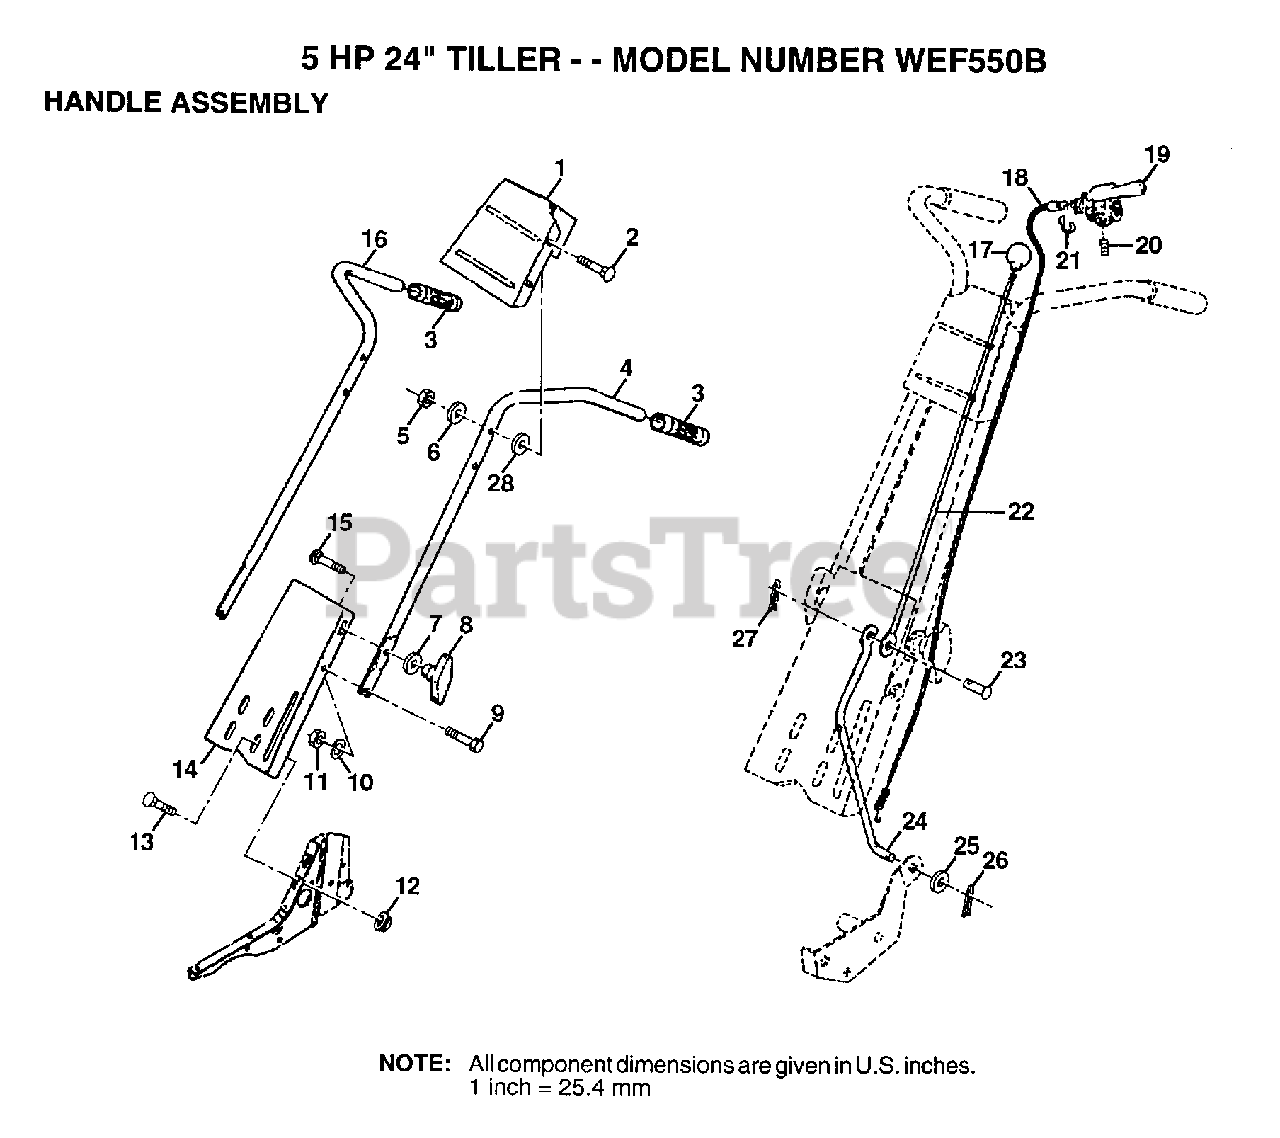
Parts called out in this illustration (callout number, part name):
1	HANDLE BRACKET
2	BOLT
6	WASHER
7	WASHER
8	KNOB HANDLE
10	LOCKWASHER
11	NUT.HEX.5/16-18
12	NUT
13	BOLT
15	BOLT
17	KNOB T(3/8 HOLE)
18	CABLE CLUTCH T
19	CONTROL LEVER TI
20	SCREW
21	E-RING
22	ROD REVERSE TI
23	RIVET.RD.HD.DRILL
24	REVERSE ROD TI
25	WASHER
26	COTTER PIN
28	WASHER
